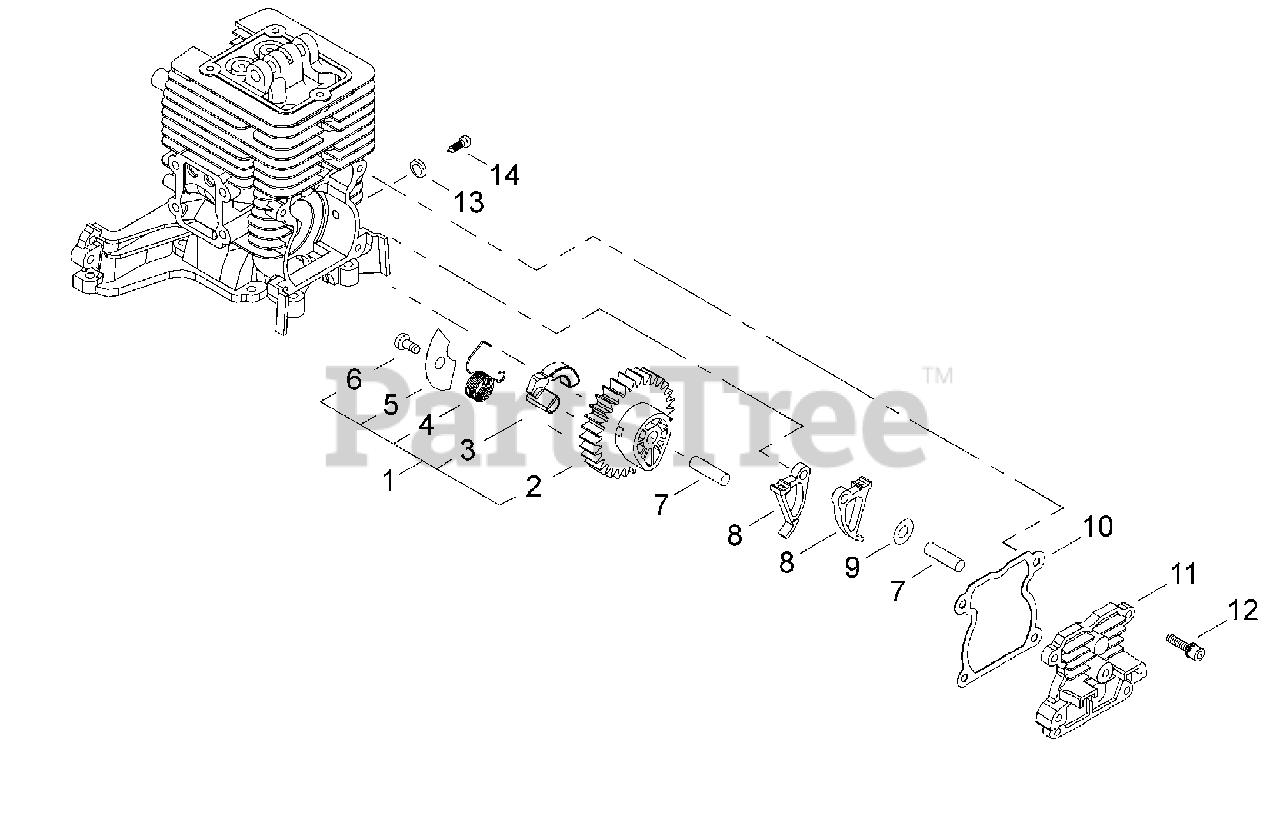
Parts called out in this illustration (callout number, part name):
1	CAM GEAR ASSY
2	GEAR, CAM
3	WEIGHT
4	SPRING
5	PLATE, COVER
6	SCREW, TAPPING 4×6
7	PIN, LOCATING Ø5×29.8 MM
8	FOLLOWER, CAM
9	WASHER 5 MM
10	GASKET, CAM GEAR
11	COVER, CAM GEAR
12	BOLT M4×14
13	WASHER Ø10ר5.5×2
14	SCREW M5
